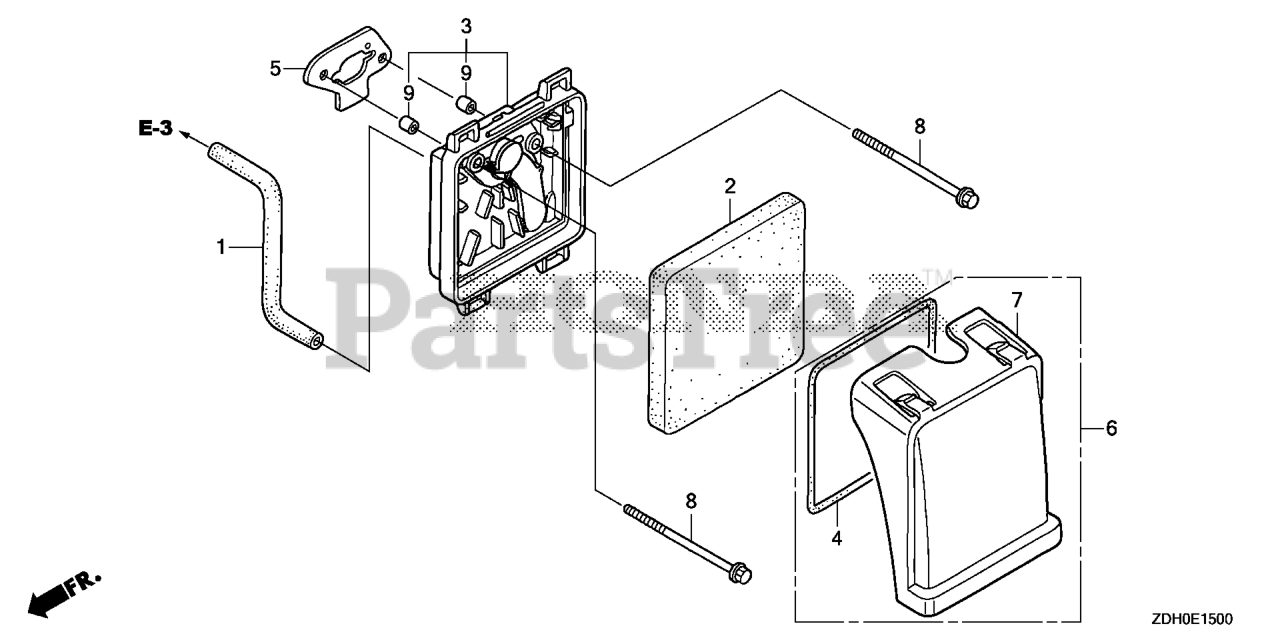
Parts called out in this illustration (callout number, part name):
1	TUBE, BREATHER
2	ELEMENT, AIR CLEANER
3	HOUSING, AIR CLEANER
4	SEAL, AIR CLEANER
5	GASKET, AIR CLEANER
6	COVER, AIR CLEANER
7	COVER, AIR CLEANER
8	BOLT, FLANGE (5X65)
9	COLLAR, AIR CLEANER
